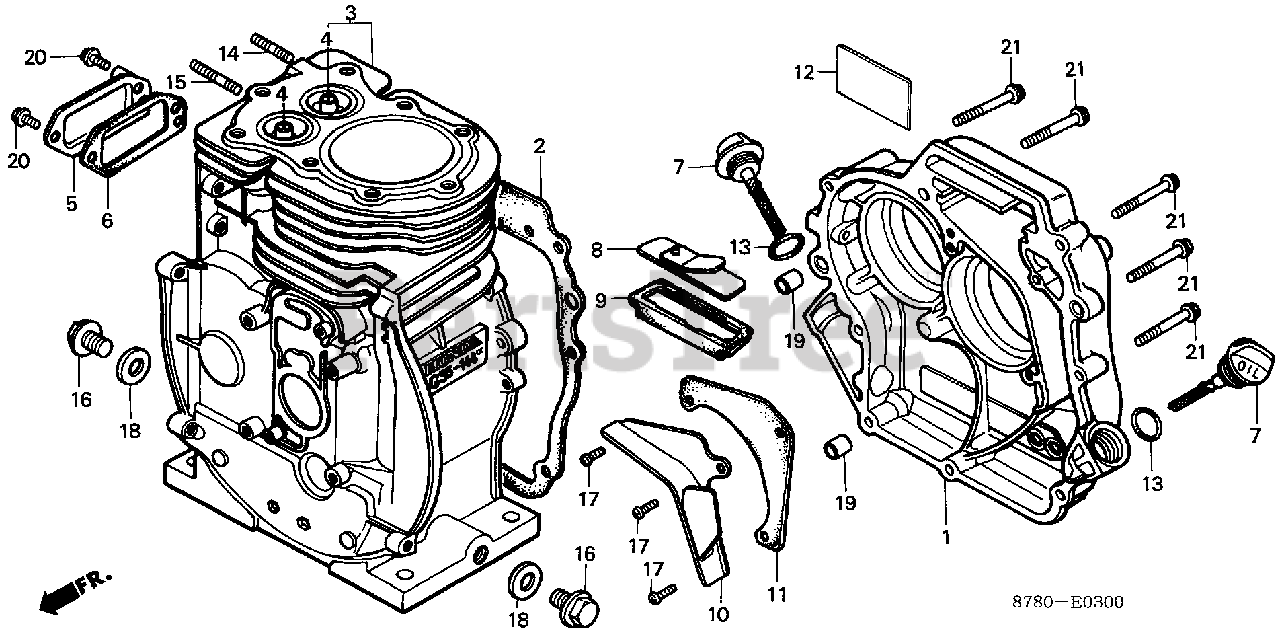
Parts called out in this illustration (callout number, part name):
1	COVER, CRANKCASE
1	COVER, CRANKCASE (NOT AVAILABLE)
2	GASKET, CRANKCASE COVER (NOT AVAILABLE)
4	GUIDE, VALVE (OVER SIZE) (NOT AVAILABLE)
5	COVER, TAPPET ROOM
6	GASKET, TAPPET COVER (NOT AVAILABLE)
7	CAP, OIL (NOT AVAILABLE)
8	PLATE, BREATHER
9	RUBBER, BREATHER PLATE
10	SEPARATOR, BREATHER
11	GASKET, SEPARATOR
13	O-RING (16MM)
14	BOLT, STUD (6X16)
15	BOLT, STUD (6X25)
16	BOLT, DRAIN PLUG (12MM)
17	SCREW, PAN (5X12)
18	WASHER, DRAIN PLUG (12MM)
19	PIN, DOWEL (8X14)
20	BOLT, FLANGE (6X12)
21	BOLT, FLANGE (6X32)
